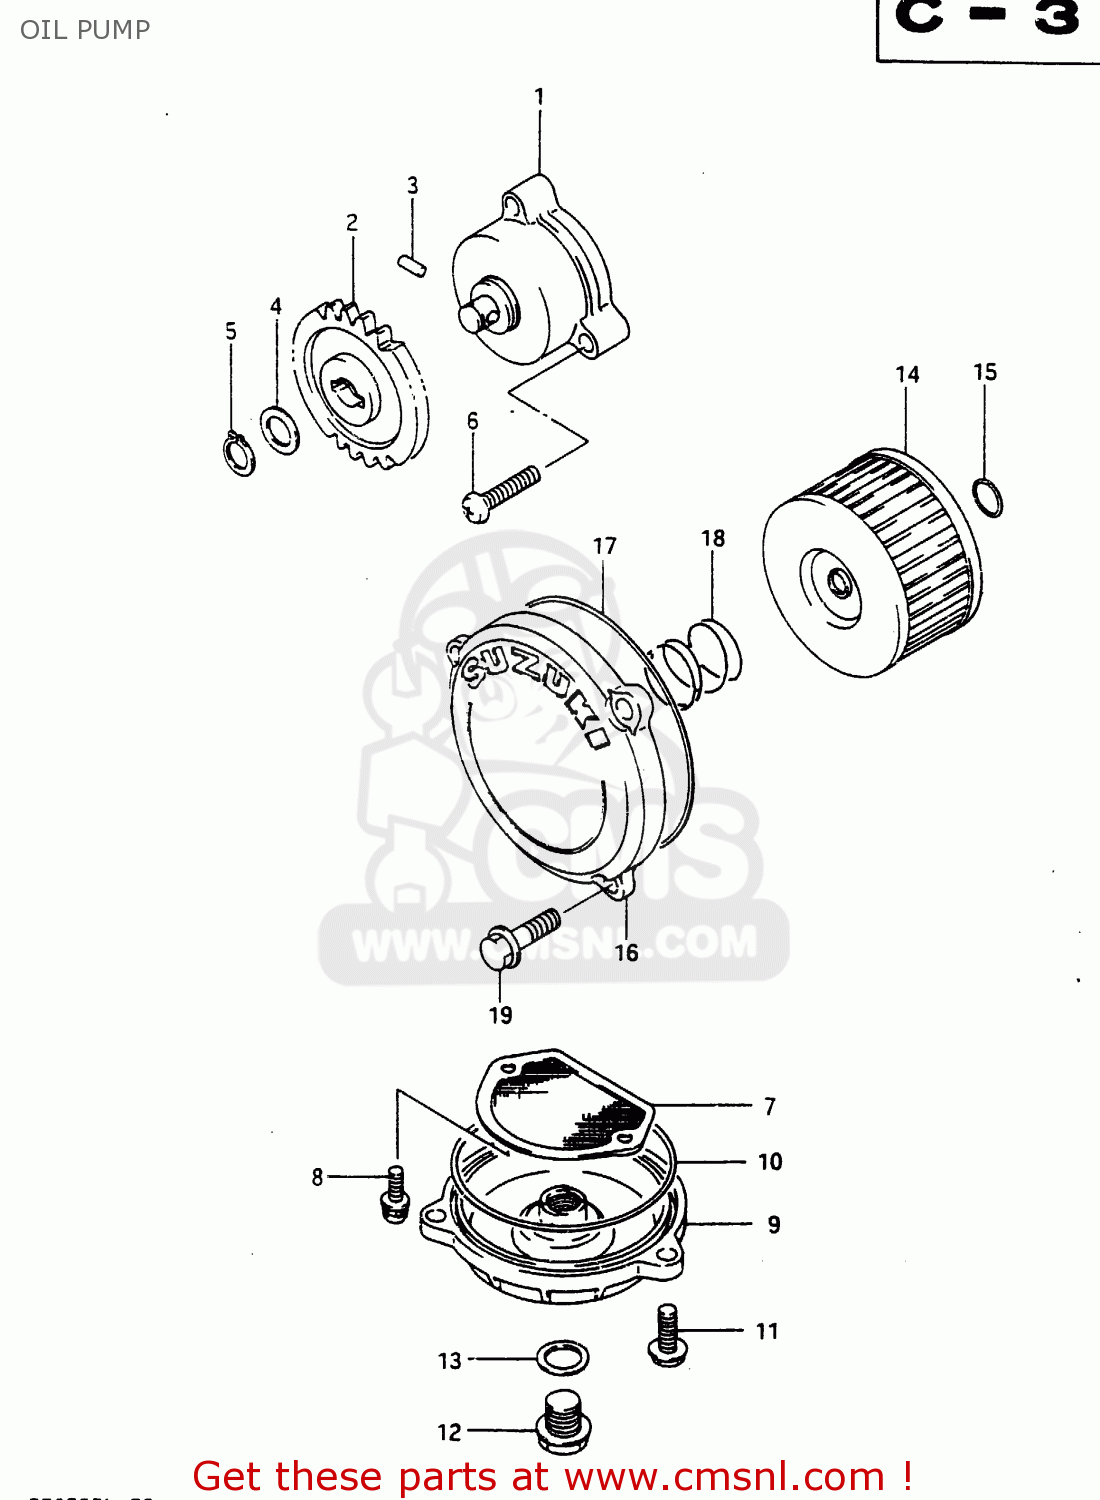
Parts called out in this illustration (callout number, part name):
1	PUMP ASSY,ENGINE OIL
2	GEAR,OIL PUMP DRIVEN
3	PIN(4X15.8)
4	SHIM
5	CIRCLIP
6	SCREW
7	STRAINER,ENGINE OIL
8	SCREW
9	CAP,OIL STRAINER
10	O RING(D:2.4,ID:85)
11	BOLT 6X20
12	PLUG
13	GASKET(14X19.2X2) (NAS)
14	FILTER,ENGINE OIL
15	O RING(D:2.4,ID:15.8)
16	CAP,OIL FILTER
17	O RING(D:2.4,ID:73)
18	SPRING
19	BOLT
